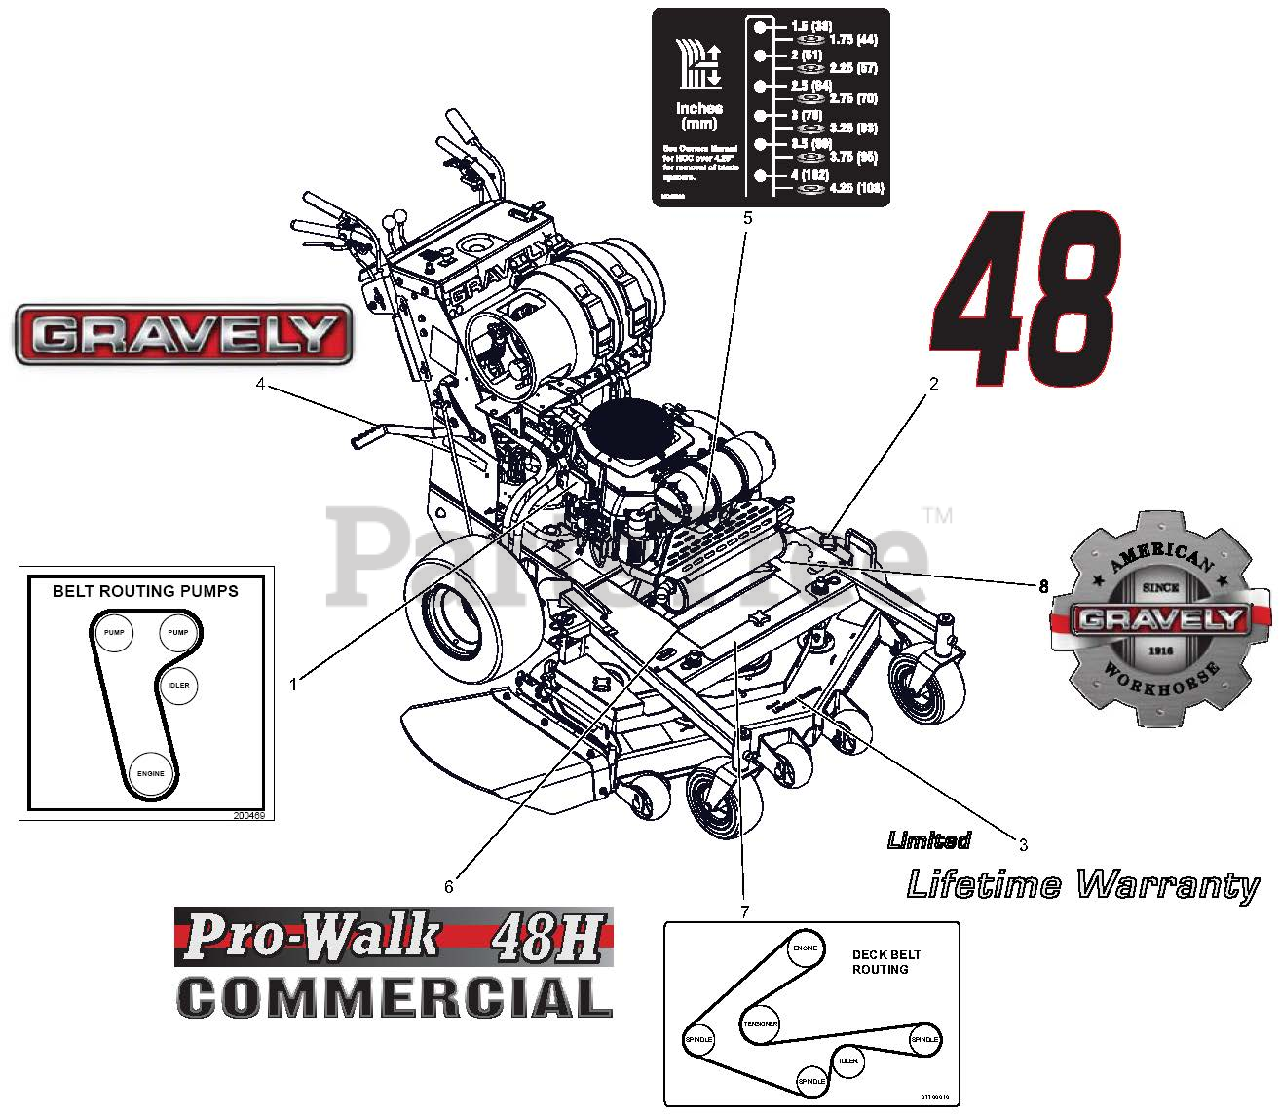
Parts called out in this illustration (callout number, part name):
1	DECAL, PUMP BELT ROUTING
2	DECAL, 48"
3	DECAL, LIMITED LIFETIME WARRANTY REV
4	DECAL, 6.5" GRAVELY LOGO
5	DECAL, PRO WALK HOC A
6	DECAL, PROWALK 48H
7	DECAL, BELT ROUTING 48/52 REV
8	DECAL, GRAVELY HERITAGE-LARGE
